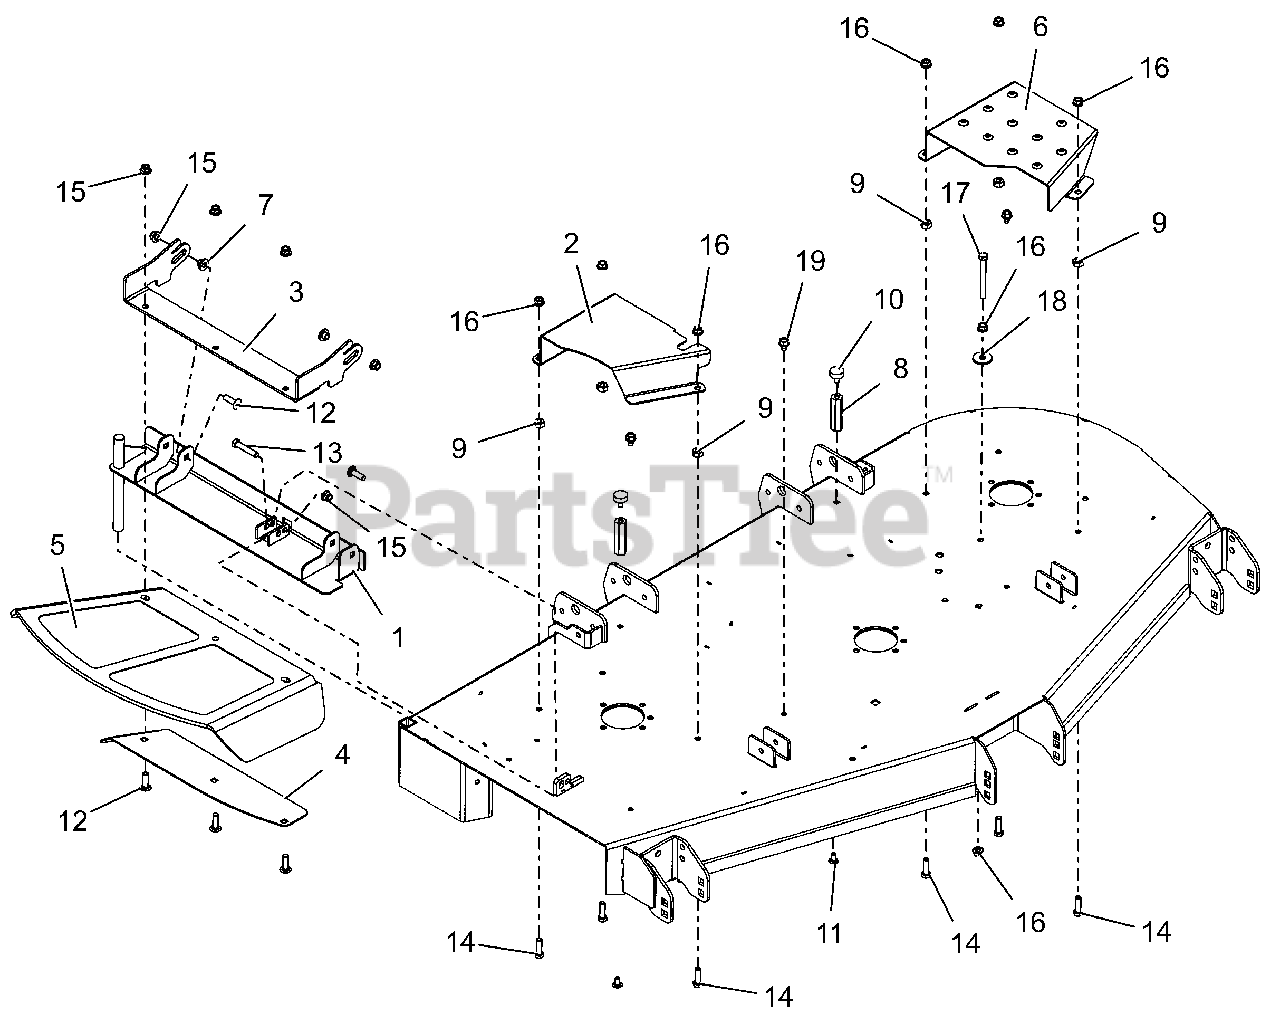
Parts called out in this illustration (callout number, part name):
1	48-60 DISCH CHT MTG WMT W/SAFE
2	GUARD,PRO-TURN DECK RH BELT-RD
3	48-60" CHUTE MTG BRKT - RED
4	48-60 DISCH CHUTE CLMP PLT-RED
5	CHUTE,48-60" FRMD RUBBER DISCH
6	GUARD,PRO-TURN DECK LH BELT-RD
7	BSHG-FLG .385X.500X.875X.406
8	NUT, COUPLING .31-18 2.75 LG
9	NUT-HEAVY HEX .38-16 YWZC
10	BUMPER, RUBBER
11	BLT-RDHDSQSHNK.31-18X.62 YZ-LK
12	@BLT-RHDSSQNK .38-16X1.25 G5YZ
13	@BLT-HEX .38-16X2.00 GR5 YWZC
14	@BLT-HEX .38-16X1.25 GR5 YWZC
15	@NUT-LK-NYL-FLG .38-16 YWZC
16	@NUT-SPNLK-FLG .375-16 YWZC
17	@BLT-HEX .38-16X3.50 GR5 YWZC
18	WSHR-FL-STL .406X1.375X.135 YZ
19	@SCR-TAP .38-16X.50 HWH TR YWZ
